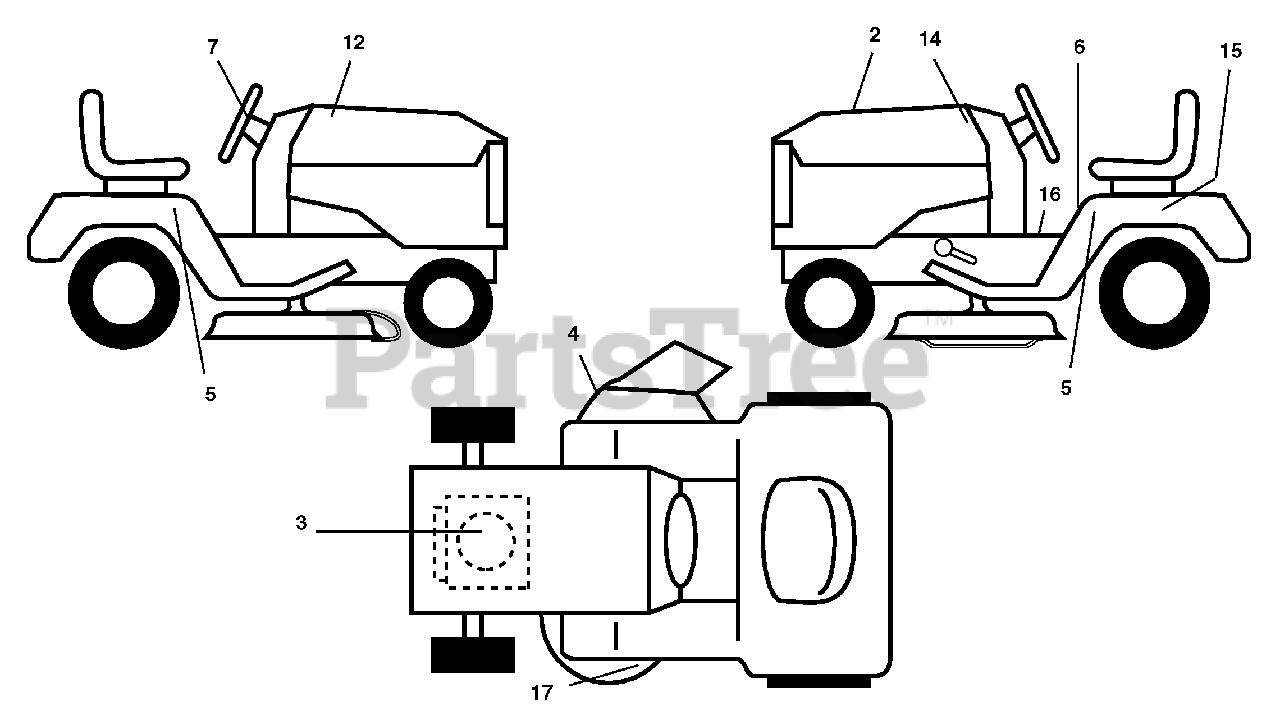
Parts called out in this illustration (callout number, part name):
2	Decal, Replacement
3	Decal, Engine HP
4	Decal Warning
5	Decal, Fender Sides
6	Decal, Fender Danger English
7	Decal Ins Str Wh
12	Decal, Hood RH
14	Decal, Hood LH
15	Decal, Caution, Battery
16	Decal, Oper Sdl P/L Gear Dr Eng
17	Decal, V-Belt Sch.
